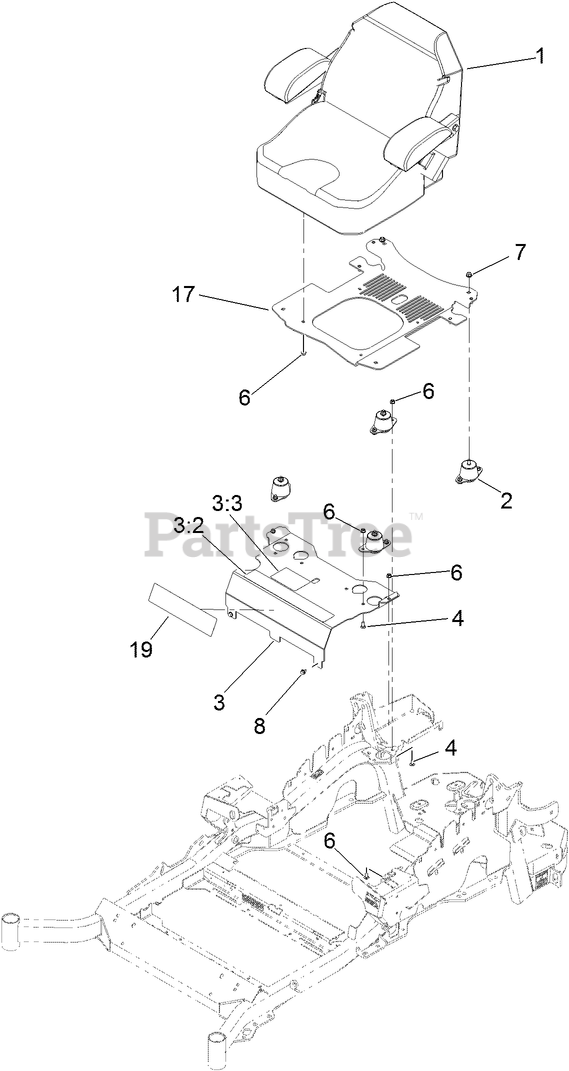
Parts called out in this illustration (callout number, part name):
1	SEAT-STANDARD
2	ISOLATOR-SEAT
3	MOUNT-SEAT
3:2	DECAL-CONSOLE
3:3	DECAL-SERVICE AID
4	SCREW-CARR
6	NUT-HF, NI
7	NUT-HF, NI
8	SCREW
17	SEAT BASE ASM
